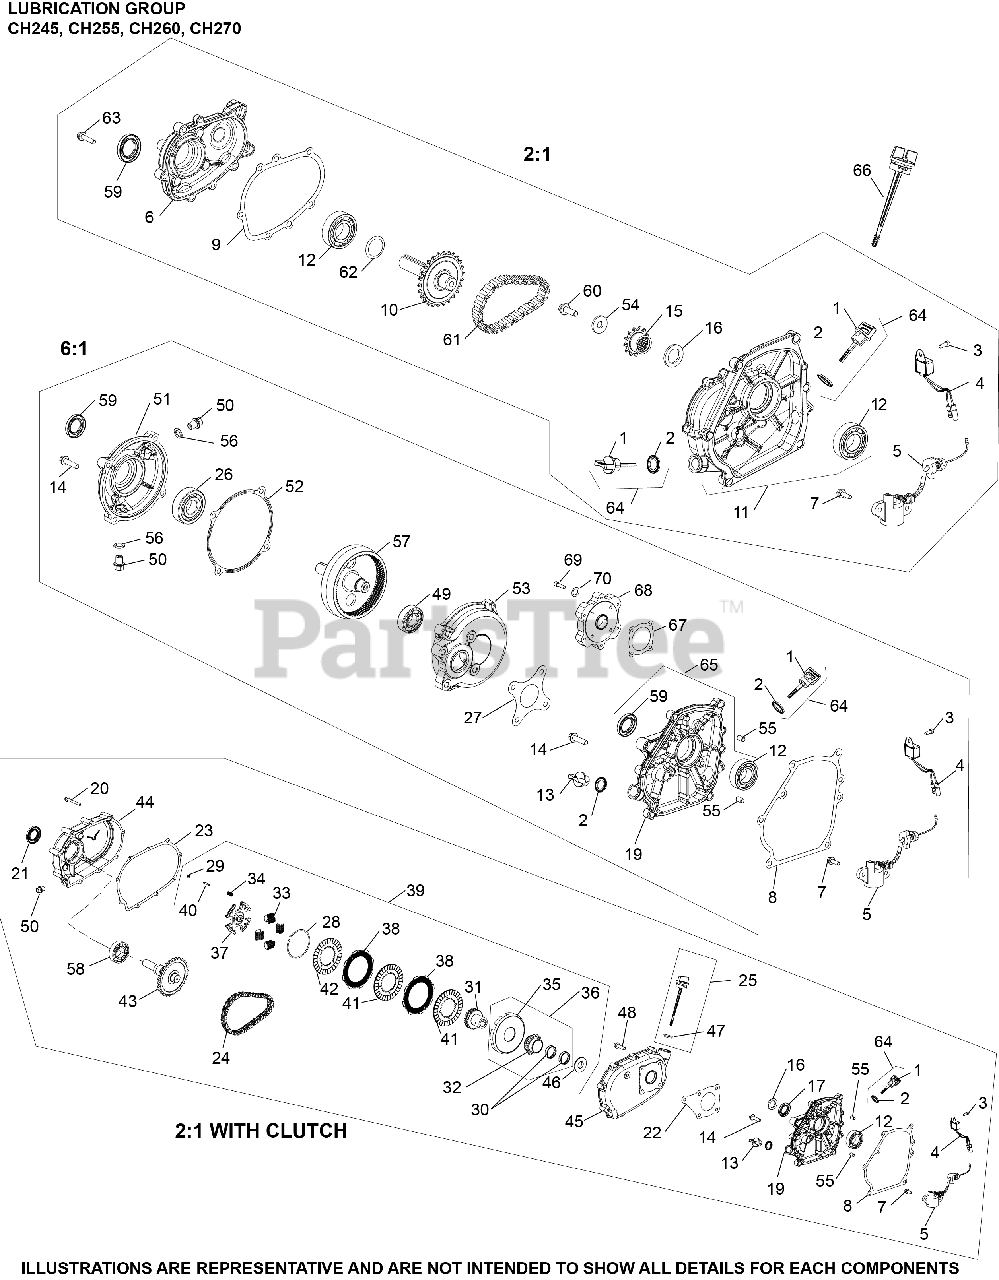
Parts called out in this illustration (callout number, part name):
1	DIPSTICK - USE 17 038 08-S
2	SEAL, OIL
3	SCREW, HEX/PHILLIPS M5
4	CONTROL, OIL ALERT UNIT
5	SWITCH, OIL SENSOR ASSEMBLY
6	COVER, CHAIN
8	GASKET, CLOSURE PLATE
9	GASKET, CHAIN COVER
10	SHAFT, PTO SPROCKET
11	PLATE , CLOSURE
12	BEARING, BALL
14	SCREW, CLOSURE PLATE
15	GEAR, PINION
16	SPACER, PINION
54	WASHER, FLAT
59	SEAL, CLOSURE PLATE
60	SCREW, HEX FLANGE (M8) (CKY)
62	WASHER, SPRING
63	SCREW, HEX FLANGE (M6)
64	DIPSTICK ASSEMBLY
